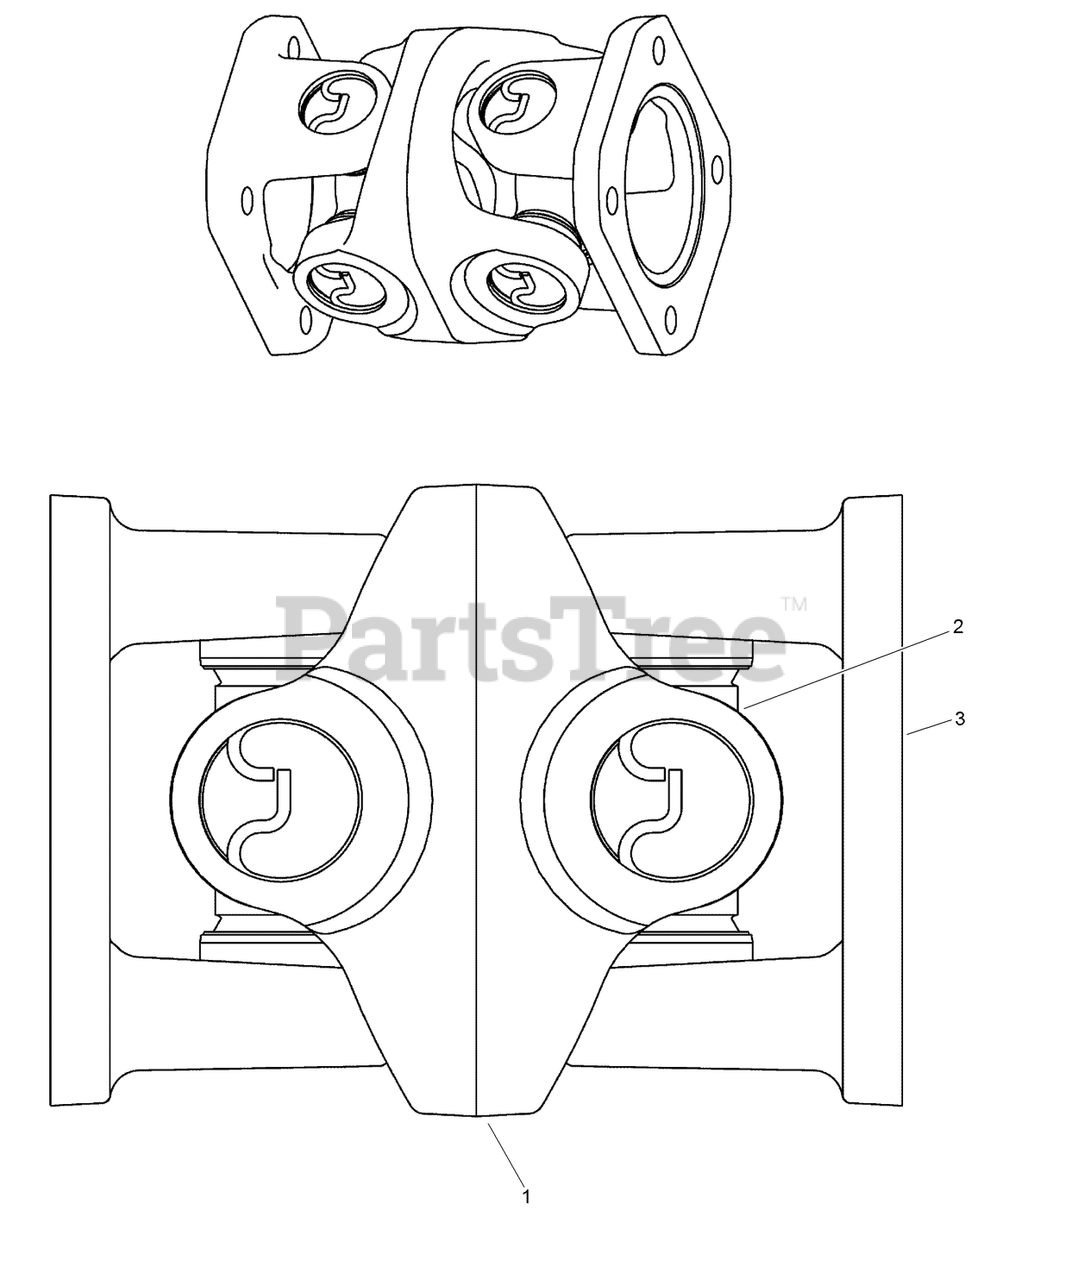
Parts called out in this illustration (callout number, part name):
1	CONNECTOR-CENTER
2	JOINT-Universal
3	FLANGE-Connection
